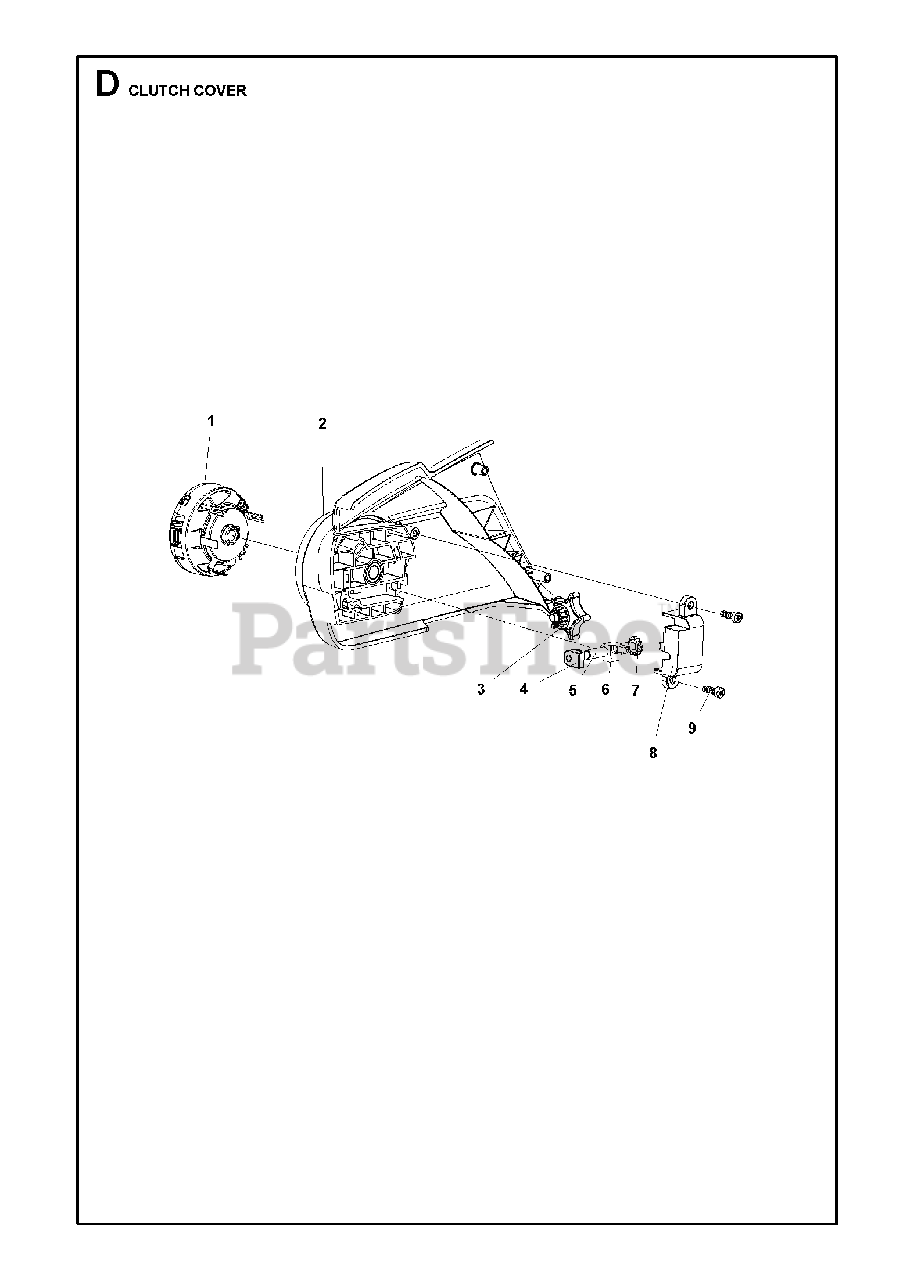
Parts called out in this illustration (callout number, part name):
1	KNOB UNLOSEABLE
2	CLUTCH COVER
3	CHAIN TENSIONER
5	SHAFT TENSION
6	PLATE ADJUSTMENT
7	PINION ADJUSTMENT
8	COVER PINION
9	SCREW ST4X12
